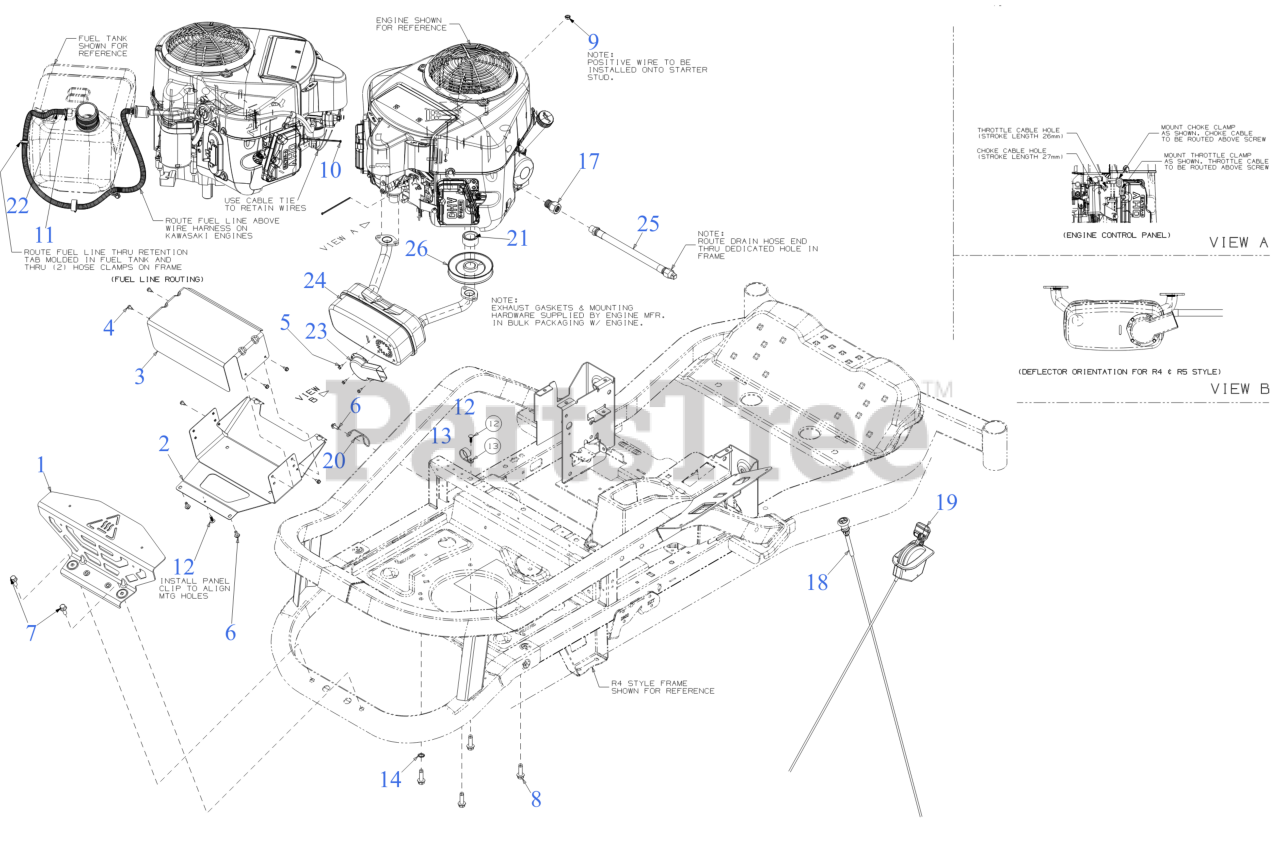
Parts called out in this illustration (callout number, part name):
1	MUFFLER COVER (REAR) (BLACK)
2	MUFFLER SHIELD (LOWER)
3	MUFFLER SHIELD (TOP)
4	HEX SCREW AB-TAP #10 x .50
5	HEX SCREW WASHER HD #8-18 x 0.500
6	SCREW M6-1 x .625
7	SCREW 5/16-18 x .875 GR5 HXFLG HD
8	SCREW 3/8-16 X1.250
9	HEX NUT 1/4-20
10	CABLE TIE
11	HOSE CLAMP 1/20
12	RATCHET CLIP (.188 x .85)
13	DRAIN HOSE CLAMP
14	LOCK WASHER 3/8
17	OIL DRAIN FITTING (M20x2.5)
18	CHOKE CABLE 41"
19	THROTTLE CABLE 38.5LG
20	HOSE GUIDE
21	ENGINE PULLEY SPACER
22	FUEL HOSE LOW PERMEATION 28"
23	EXHAUST DELECTOR (LONG)
24	EXHAUST MUFFLER (TWIN)
25	OIL DRAIN HOSE (11.26" 3/8 NPT)
26	TRANSMISSION DRIVE PULLEY
